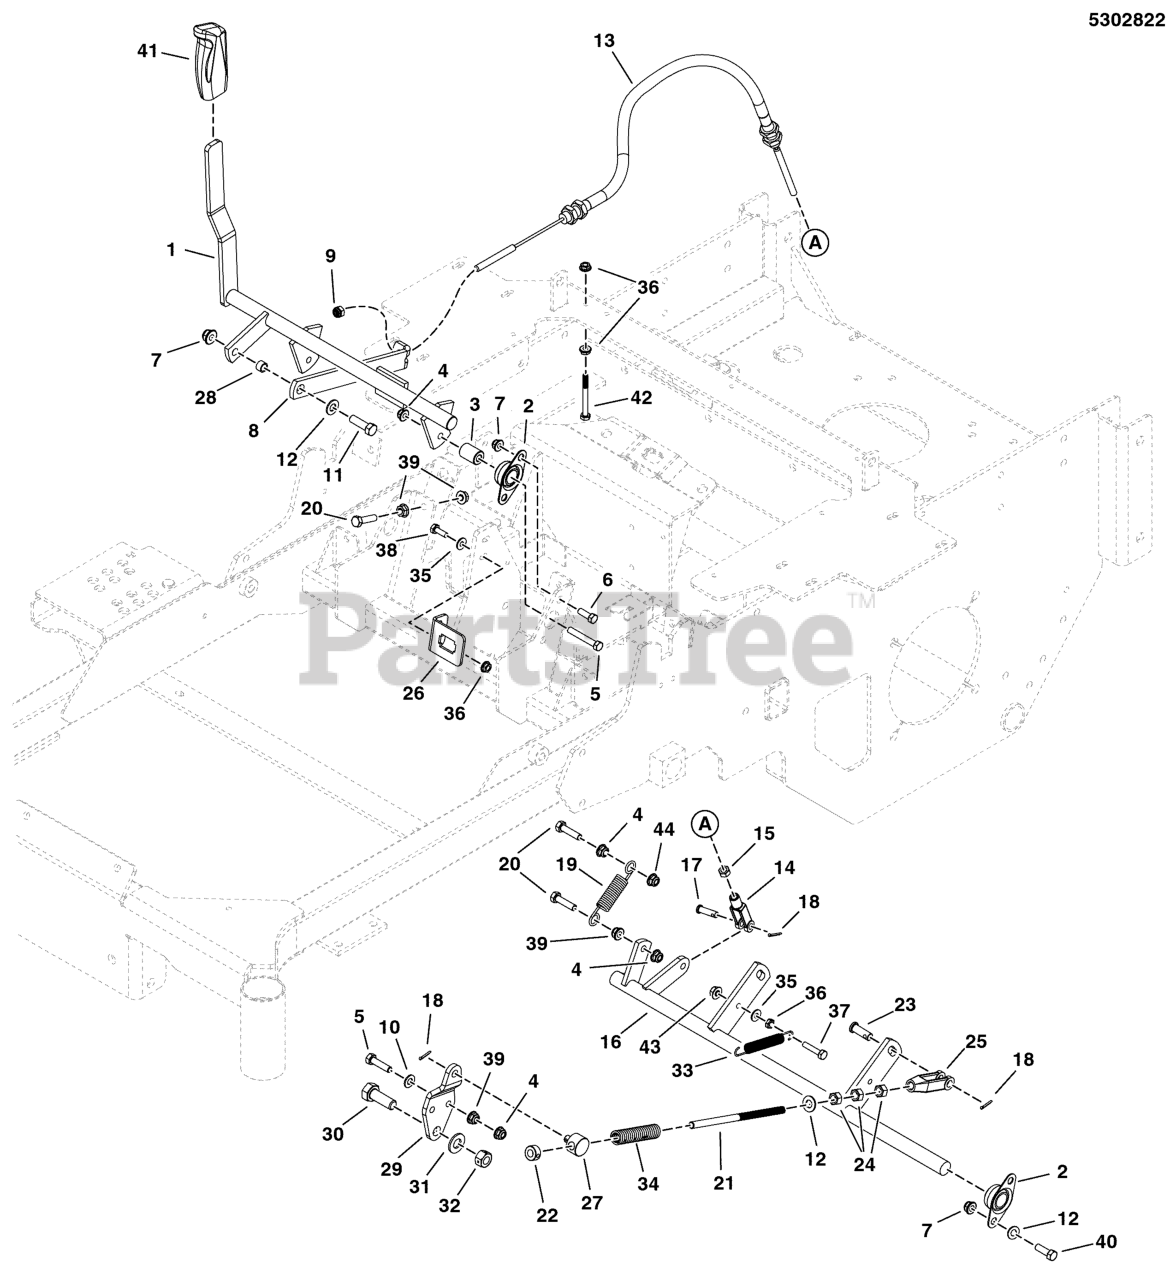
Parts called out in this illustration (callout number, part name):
1	WELD, BRAKE - BLK
2	BEARING, BRONZE FLANGE, 3/4
3	SPACER, .32 X .75 X 1.06
4	NUT, 5/16-18 HEX NYLOCK FLANGE
5	BOLT, 5/16-18 X 1-3/4 GD5 YZ
6	BOLT, 3/8-16 X 3/4" GD5 CZ
7	NUT, 3/8-16 HEX NYLOCK FLANGE
8	LINK, BRAKE LOCK - BLK
9	NUT, 5/16-24 HEX NYLON LOCK
10	WASHER, 5/16" SAE
11	BOLT, 3/8-16 X 1-1/4" GD5 CZ
12	WASHER, 3/8 SAE
13	CABLE, PARKING BRAKE IS2000
14	CLEVIS, 5/16-24, STEEL, CLEAR ZINC
15	NUT, 5/16-24 HEX
16	WELD, BRAKE REAR - BLK
17	PIN-CLEVIS, 5/16 X 1 YZ
18	PIN, 3/32 X 0.750, COT, ZINC/CLEAR
19	SPRING, EXTENSION
20	BOLT, 5/16-18 X 1-1/4 GD5 YZ
21	ROD, BRAKE ADJUSTMENT, CZ
22	COLLAR, 3/8 SET
23	PIN, CLEVIS, 3/8 X 1-1/8, CZ
24	NUT, 3/8-24 HEX JAM
25	CLEVIS 3/8-24 STEEL
26	BRACKET, SWITCH MOUNT - BLK
27	ADJUSTER, BRAKE LINKAGE
28	SPACER, .38 X .50 X .31, CZ
29	PLATE, BRAKE ARM EXTENSION - BLK
30	BOLT, 1/2-13 X 1-1/2 GD5 CZ
31	WASHER, 1/2 SAE
32	NUT, 1/2-13 HEX SIDE LOCK
33	SPRING, EXTENTION, .50 OD X 4.12 FL
34	SPRING-COMP, .496ID X 3.00LG X .112WR
35	WASHER, 1/4 SAE
36	NUT, 1/4-20 HEX SERR. FLANGE
37	BOLT, 1/4-20 X 1-1/4, GD5
38	BOLT, 1/4-20 X 3/4, GD5
39	NUT, 5/16-18 HEX SERRATED FLANGE (SMALL)
40	BOLT, 3/8-16 X 1" GD5 CZ
41	GRIP, BLACK FLEXIBLE
42	BOLT, 5/16-18 X 3-3/4 GD5 YZ
43	NUT, 1/4-20 HEX NYLOCK FLANGE
44	NUT, 5/16-18 HEX NYLON LOCK
